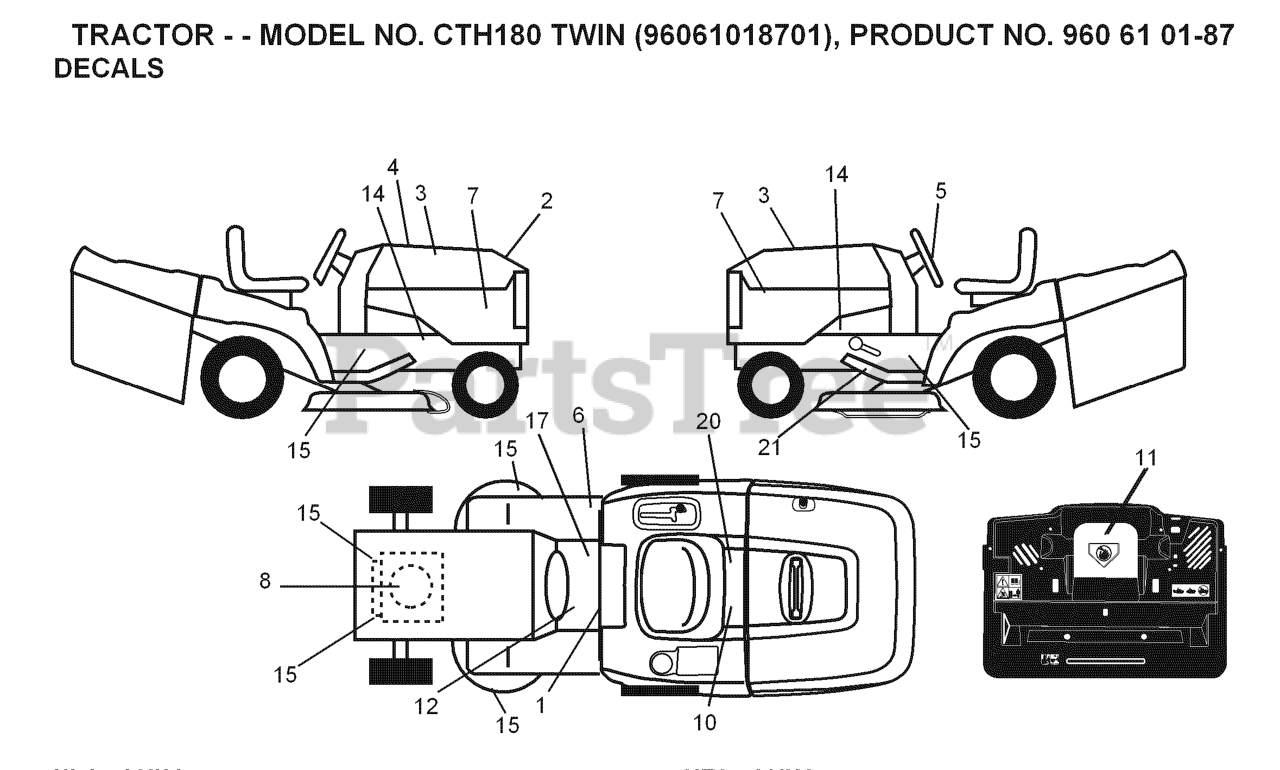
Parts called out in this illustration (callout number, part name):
1	LABEL
2	DECAL.HOOD.TOP.INSERT.
3	DECAL.HOOD.NAMELOGO.HUSQ
5	DECAL.WHEEL.STRG.LGN.H
6	Decal, Fender 100 DB/CE
8	DECAL
10	DECAL BTRY SYMBOLS
11	DECAL.INTERNATIONL.CUTFINGER
12	DECAL
17	DECAL PARK BRAKE
20	DECAL.BYPASS.FENDER.CRD.LT.YT
